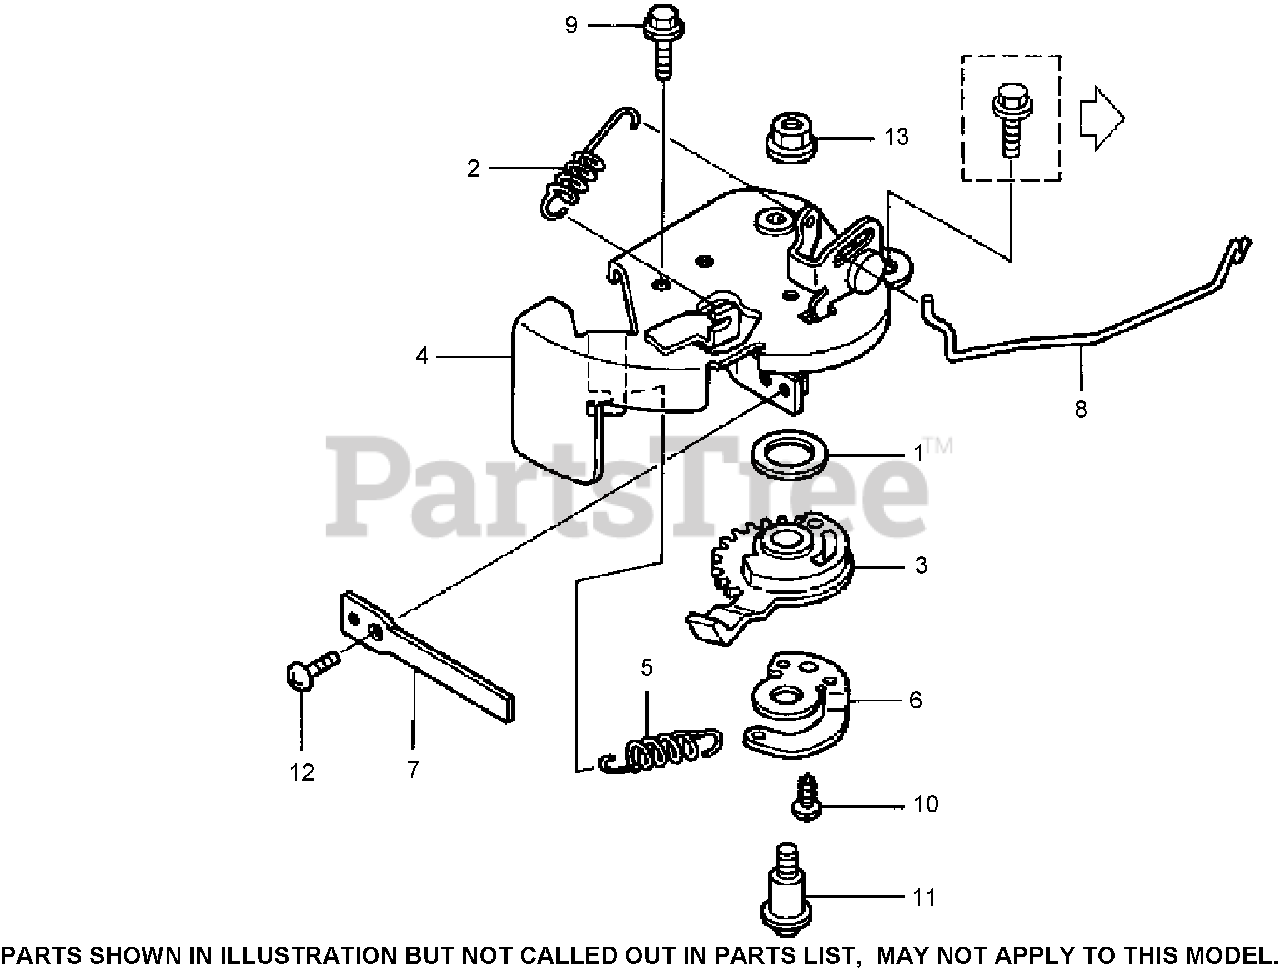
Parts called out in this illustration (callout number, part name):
1	SEAL, CHOKE LEVER
2	SPRING, CABLE RETURN
3	LEVER, CHOKE
4	BASE, CHOKE
5	SPRING, CHOKE LEVER
6	HOOK, CHOKE SPRING
7	PLATE, CHOKE
8	ROD, STOP
9	BOLT, FLANGE (6X16)
10	SCREW, TAPPING (4X8) (PO)
11	SCREW, PAN (5X19)
12	SCREW, PAN (4X8)
13	NUT, FLANGE (5MM)
